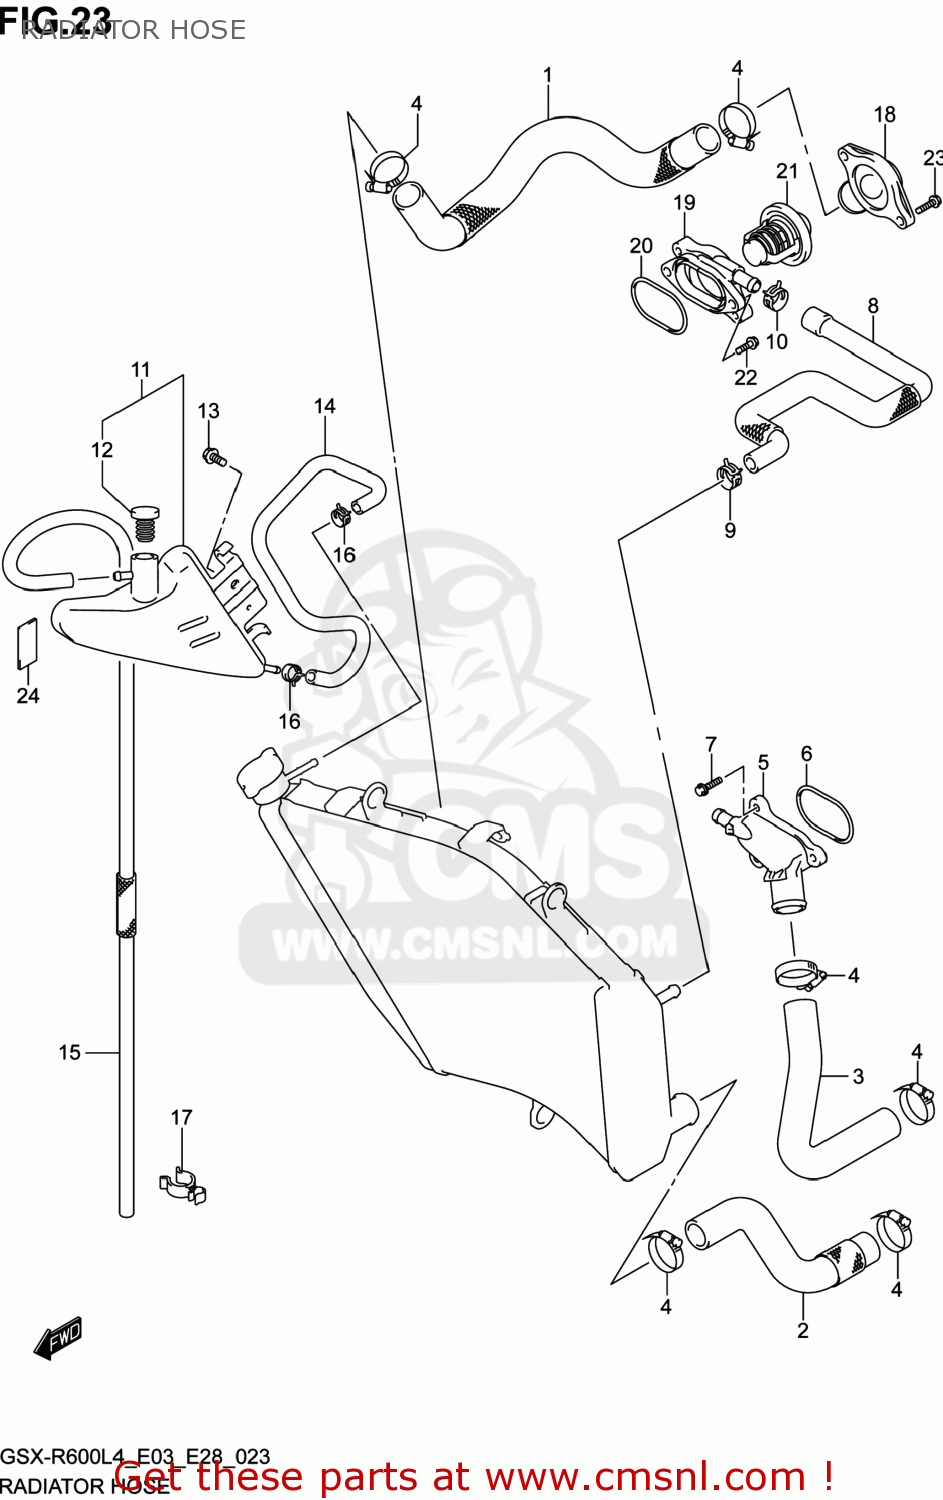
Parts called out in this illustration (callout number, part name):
1	HOSE,RADIATOR INLET
2	HOSE,RADIATOR OUTLET
3	HOSE,CYLINDER INLET
4	CLAMP
5	CONNECTOR,CYLINDER WATER INLET
6	O RING,CYL WATER CONNECTOR
7	BOLT
8	HOSE,WATER BYPASS
9	CLAMP
10	CLIP
11	TANK ASSY,RESERVOIR
12	CAP,RESERVOIR TANK
13	BOLT(6X12)
14	HOSE,RESERVOIR TANK INLET
15	HOSE,RESERVOIR TANK OVFL
16	CLIP
17	CLAMP(L:45)
18	COVER,THERMOSTAT
19	CONNECTOR,THERMOSTAT
20	O RING,THERMOSTAT CONNECTOR
21	THERMOSTAT,WATER 82 DEG
22	BOLT
23	BOLT
24	CUSHION,FR
